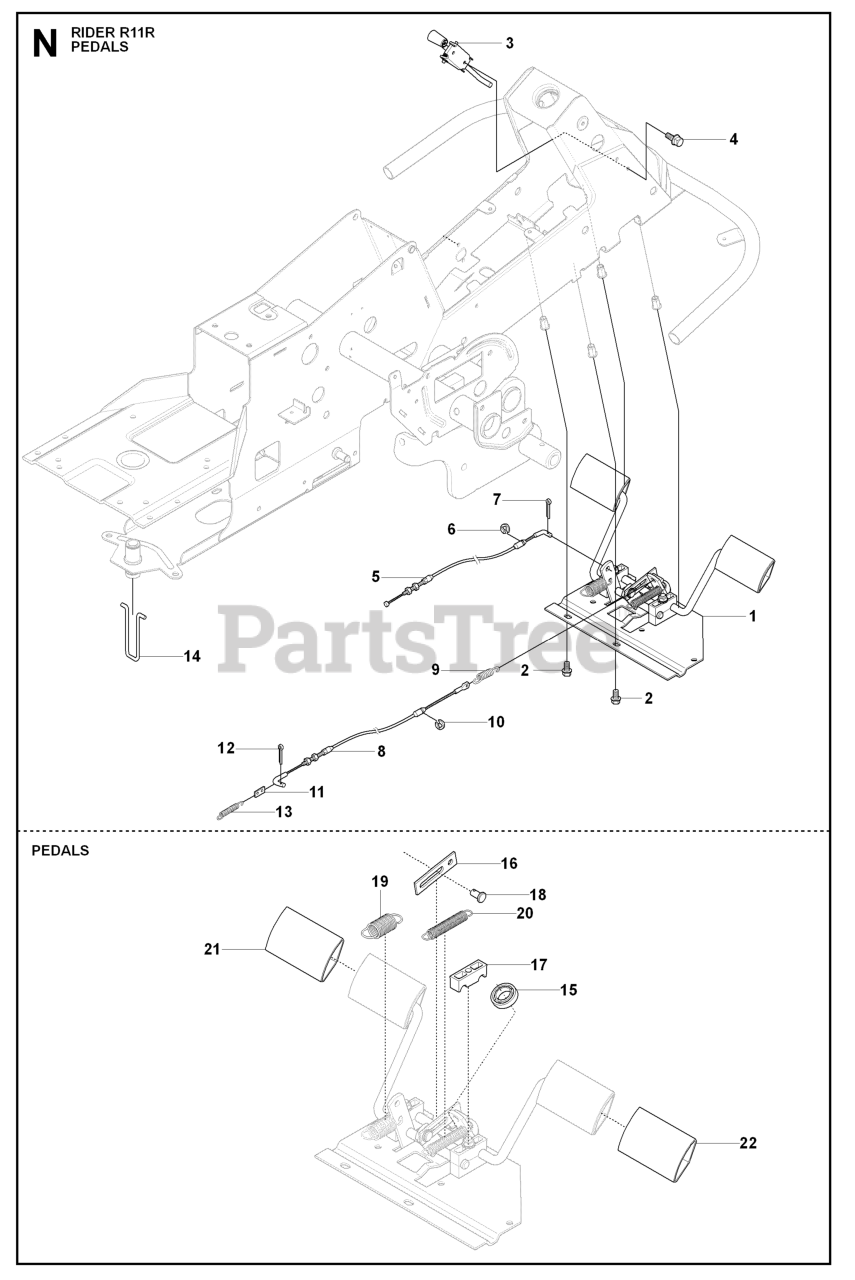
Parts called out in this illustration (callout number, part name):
1	PEDAL PLATE ASSY MANUAL
3	BRAKE LEVER ASSY
7	Cotter Pin
12	Cotter Pin
15	BALL BEARING 6002-2RS1
17	PEDAL SHAFT CLAMP
18	Clevis Pin
21	PEDAL RUBBER, SF
22	PEDAL RUBBER, SF
